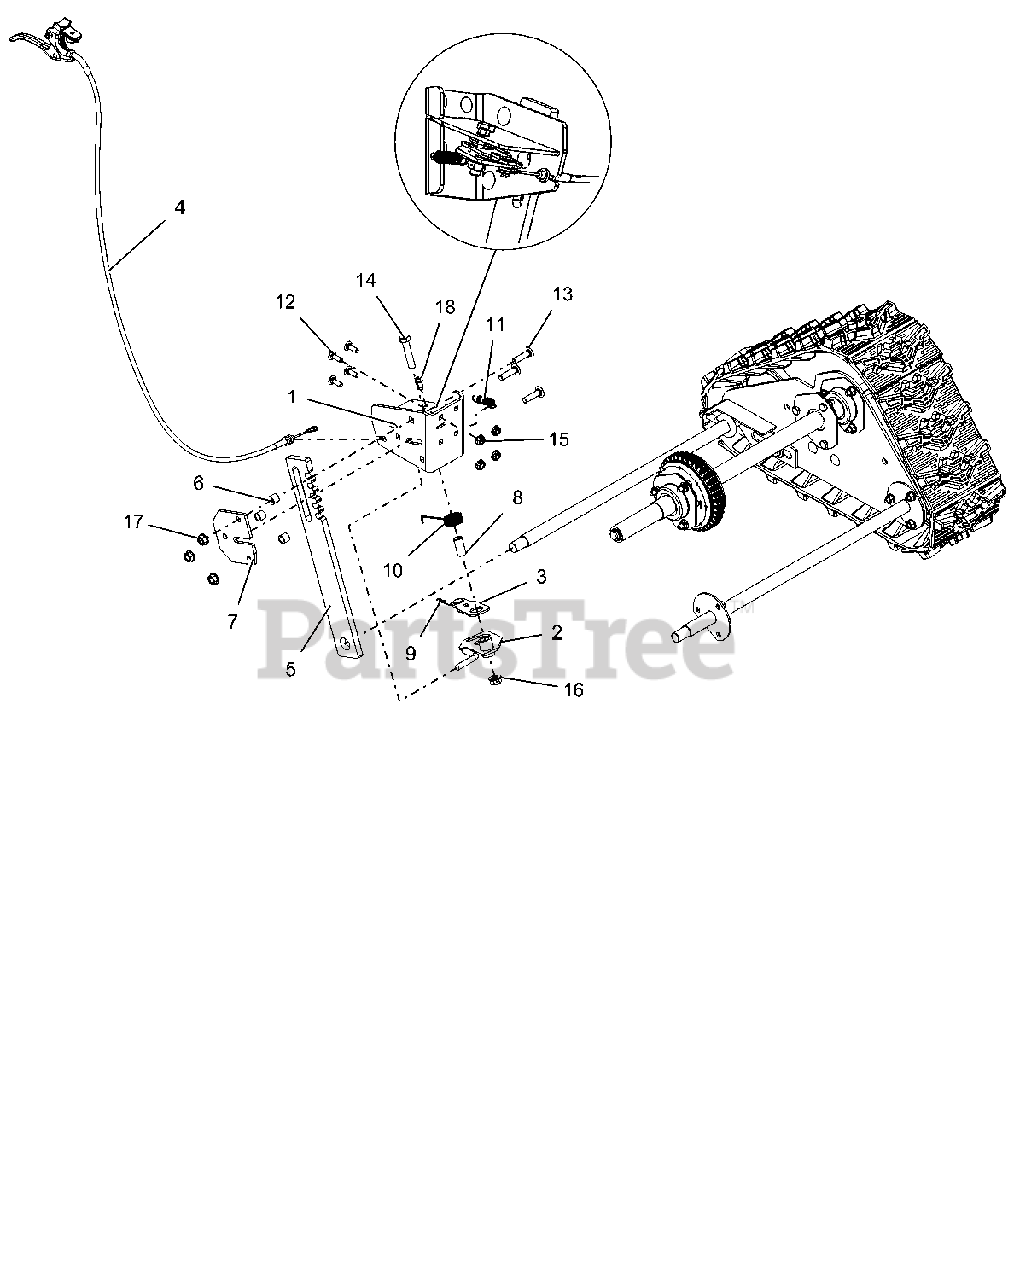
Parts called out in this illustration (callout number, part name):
1	BRACKET, HEIGHT ADJUSTER-PRO
2	LOCK, HEIGHT ADJUSTER
3	ARM, OVERTRAVEL
4	CABLE, TRACK REMOTE
5	STOP, HEIGHT ADJUSTER-PRO
6	SPACER .50 X .32 X .42
7	PLATE, HEIGHT ADJUSTER
8	BSHG-SLV .385X.500X1.045
9	PIN-HAIR INT .06X.18X.77
10	SG-TORS .067X.88
11	SPRING-EXT .047 X .438 X 1.85
12	@BLT-RDHDSQNK .25-20X.75 G5YZ
13	@BLT-RHDSHSQNK.31-18X1.25 G5YZ
14	@BLT-HEX .38-16X1.75 GR5 YWZC
15	@NUT-LK-CTR-FLG .25-20 YWZC
16	NUT-LK-CTR-FLG .38-16 YWZC
17	@NUT-LK-TOP-FLG .31-18 YWZC
18	SCR-TAP .25-20X.50 HWH TR YWZ
